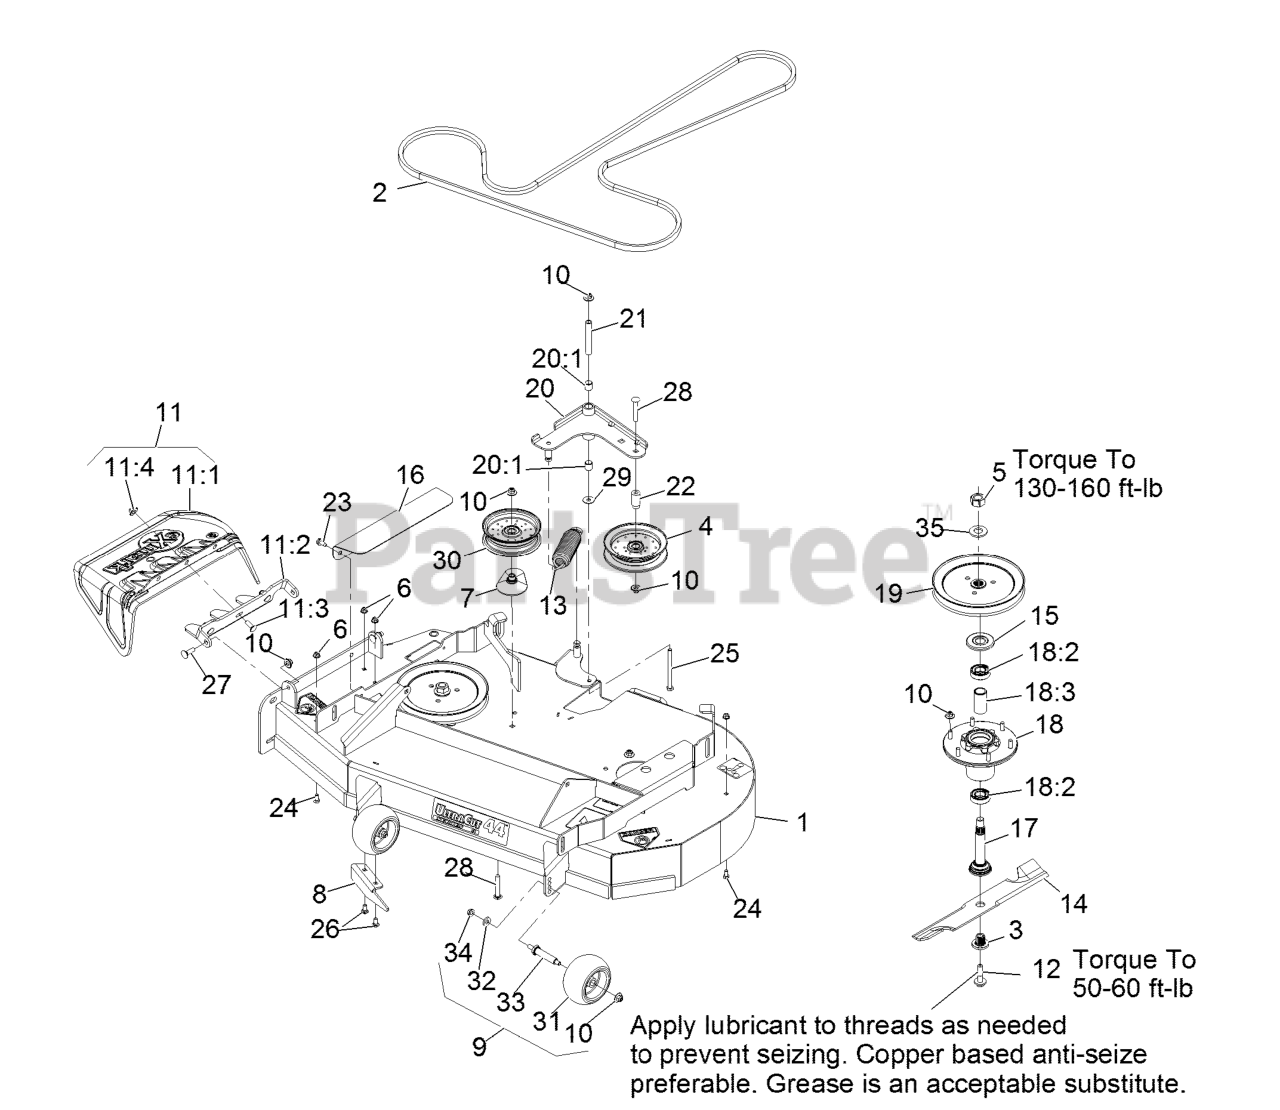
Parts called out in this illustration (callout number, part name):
1	ASM-DECK W/DECALS 44
2	BELT - V, B
3	BUSHING,SPLINED
5	NUT-HEX
6	NUT-HF, NI
7	SPACER-PULLEY
8	BAFFLE-DISCHARGE
10	Nut-Nyloc 3/8-16 Flg
11	ASM,DISCHARGE CHUTE
11:1	CHUTE,DISCHARGE
11:2	BRACKET,DISCHARGE CHUTE
11:3	SCREW-CARR
11:4	Nut-Nyloc 3/8-16 Flg
12	SCREW,SEMS 1/2-20 X 2.19
13	SPRING-EXTENSION
14	Blade-Mulch, 22.25
14	Blade-Notched, 22.25
15	GUARD,BEARING TOP .989
16	COVER,BELT
17	ASM-SPINDLE AND SEAL
18	ASM-CUTTER HSG WITH BEARINGS
18:2	BEARING-BALL
18:3	SPACER-BEARING
19	SHEAVE-BLADE DRIVE, 8.40
20:1	SLEEVE-BEARING
21	BUSHING
22	BUSHING-IDLER
23	Screw-HWH 5/16-18 X 3/4 Tf
24	SCREW-HH
25	SCREW-HH
26	BOLT-CARR
27	BOLT-CARR
28	SCREW-CARR
30	IDLER-PULLEY, FLAT
31	ROLLER-SCALP, ANTI
32	WASHER-BELLEVILLE
34	NUT-HHF, WHIZ
